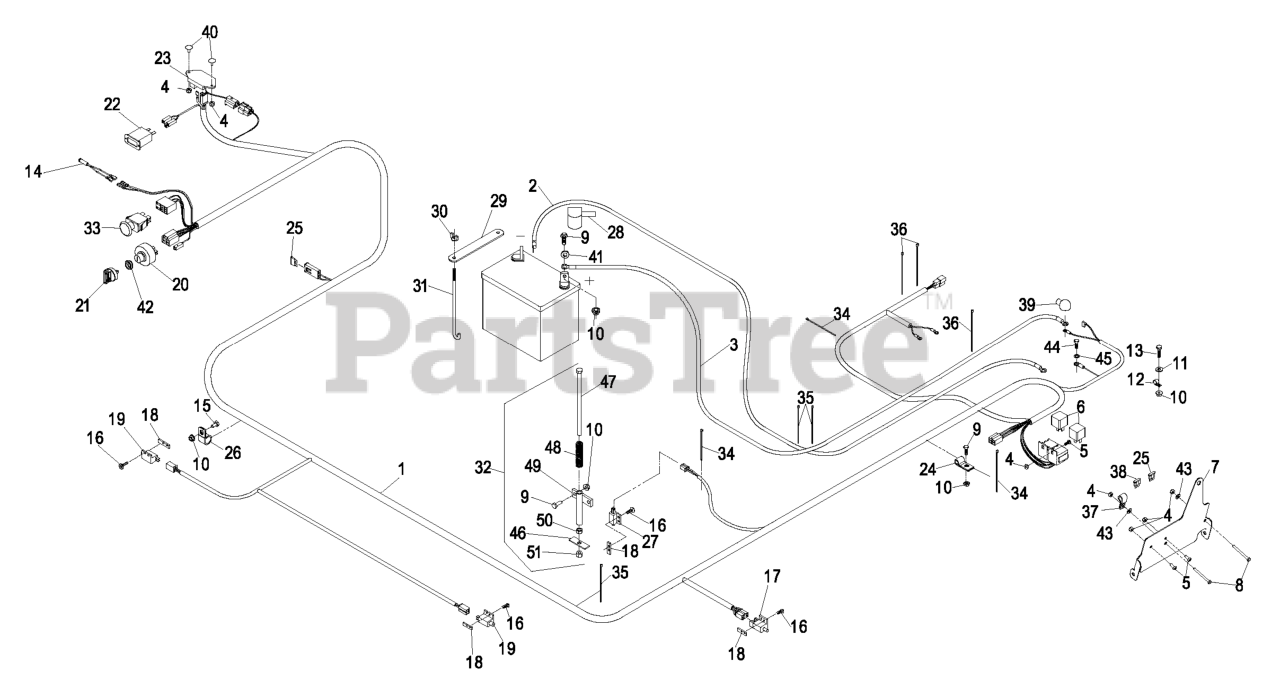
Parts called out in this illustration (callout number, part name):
1	HARNESS, WIRE LAZER EFI
2	WIRE-GROUND
4	NUT-LOCK, NI
7	PANEL-EFI
8	SCREW-HH
9	SCREW-HH
11	WASHER-FLAT
12	CLIP-LOOM
13	SCREW-HH
14	INDICATOR-LED, RED
15	SCREW-HH
16	SCREW-PPH
18	PLATE-TAPPED
19	SWITCH-OPEN, NORMALLY
21	KEY-IGNITION
22	METER-HOUR
23	MODULE-DELAY, SEAT
24	CLIP-LOOM
25	FUSE-BLADE TYPE, 20 AMP
26	CLIP-LOOM
27	SWITCH-CLOSED, NORMALLY
29	STRAP-HOLDDOWN, BATTERY
30	WINGNUT
31	BOLT-HOLDDOWN
32	ASM,SEAT SWITCH ACTUATOR
33	SWITCH-PTO
34	TIE-CABLE
35	TIE-PLASTIC
36	TIE-PLASTIC
37	CLIP-LOOM
39	INSULATOR-SOLENOID
40	BOLT-CARR
41	WASHER-FLAT
42	NUT-SWITCH, IGNITION
43	WASHER-FLAT
44	SCREW-HH
45	WASHER-PLAIN
46	PLATE-SWITCH, SEAT
47	SCREW-HH
48	SPRING-SWITCH, SEAT
49	MOUNT-SPRING, SEAT
50	NUT-HEX
51	NUT-LOCK, NI
